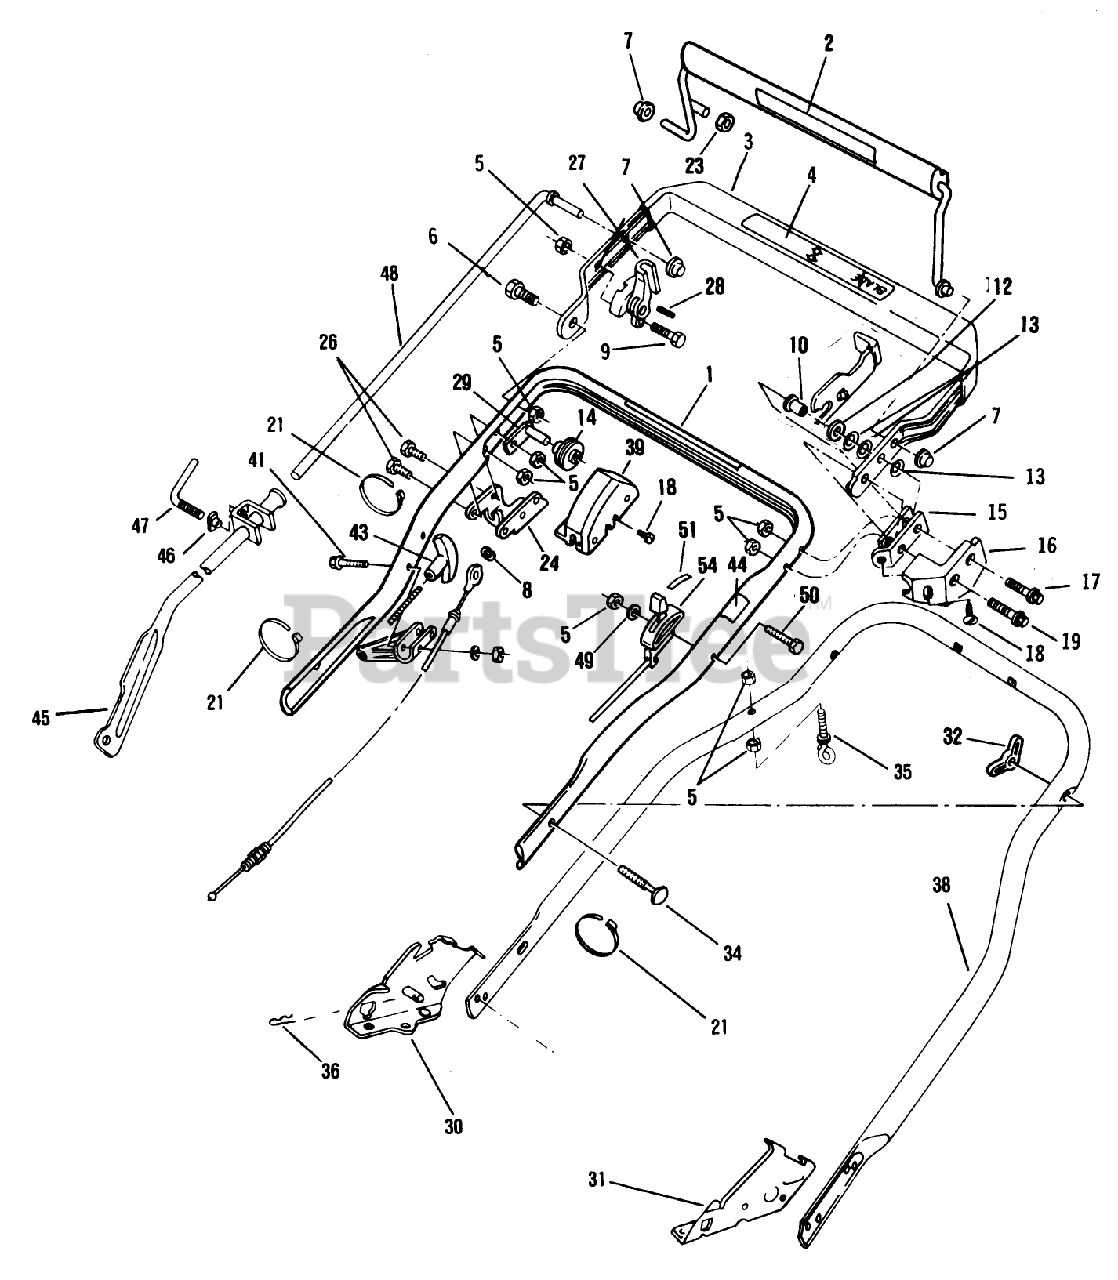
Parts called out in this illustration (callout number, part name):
5	LOCKNUT E
6	BOLT
8	RET. RING
10	SPACER
12	WASHER M
14	PULLEY PL
15	DOWN STOP
16	LOCKOUT GUARD
17	BOLT SHOU
18	SCREW F
19	SCREW
23	NUT ACORN
30	BRACKET ASM - HANDLE, SP, RH
31	BRACKET ASM - HANDLE, SP, LH
32	BOLT QUALITY
33	CONTROL CABLE
34	NUT-WING
35	EYE BOLT WAS MFG
36	HAIR PIN
37	HANDLE SECTION
40	WASHER
43	HANDLE START UM&D
45	CONTROL LEVER AY
48	CONTROL ROD
49	WASHER-FLAT
